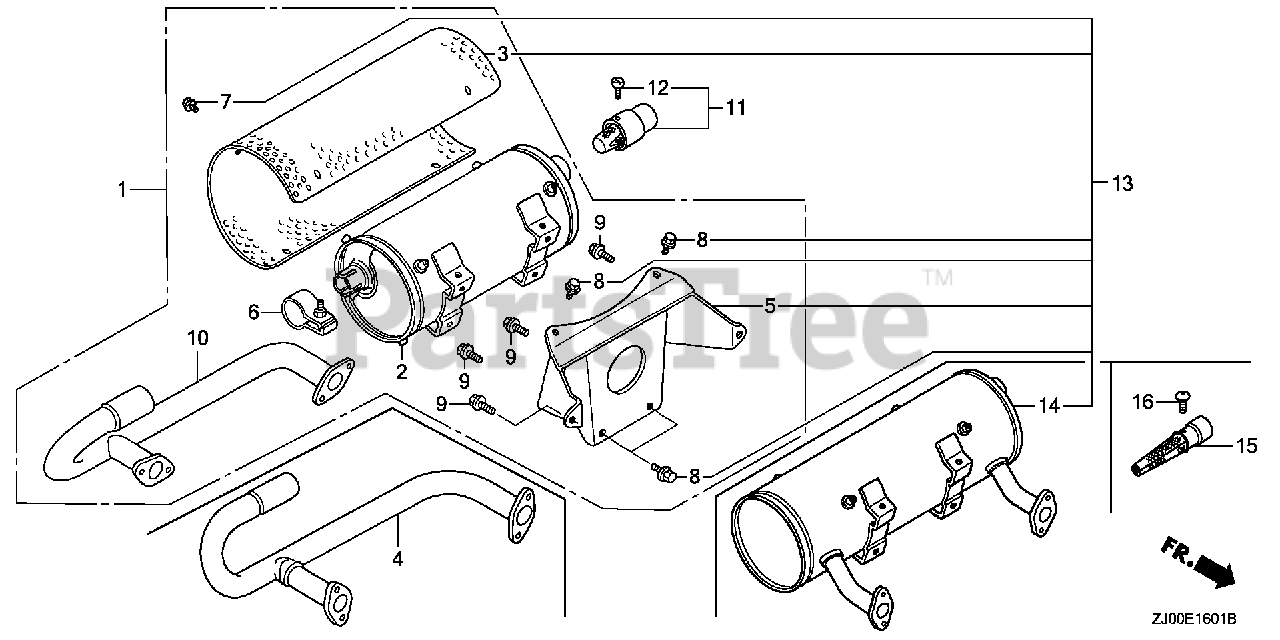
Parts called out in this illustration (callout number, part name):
1	MUFFLER KIT (HIGH-B) (N/A: SEE COMPONENTS)
2	MUFFLER COMP. (HIGH-R) (NELSON) (BLACK MUFFLER)
3	PROTECTOR, MUFFLER (HIGH) (FUTABA) (FOR BLACK MUFFLER)
4	PIPE, EX. (HIGH-L)
5	STAY, MUFFLER (HIGH-NELSON)
6	BAND ASSY. (NOT AVAILABLE)
7	BOLT, FLANGE (6X8)
8	BOLT, FLANGE (8X14)
9	BOLT, FLANGE (8X20)
